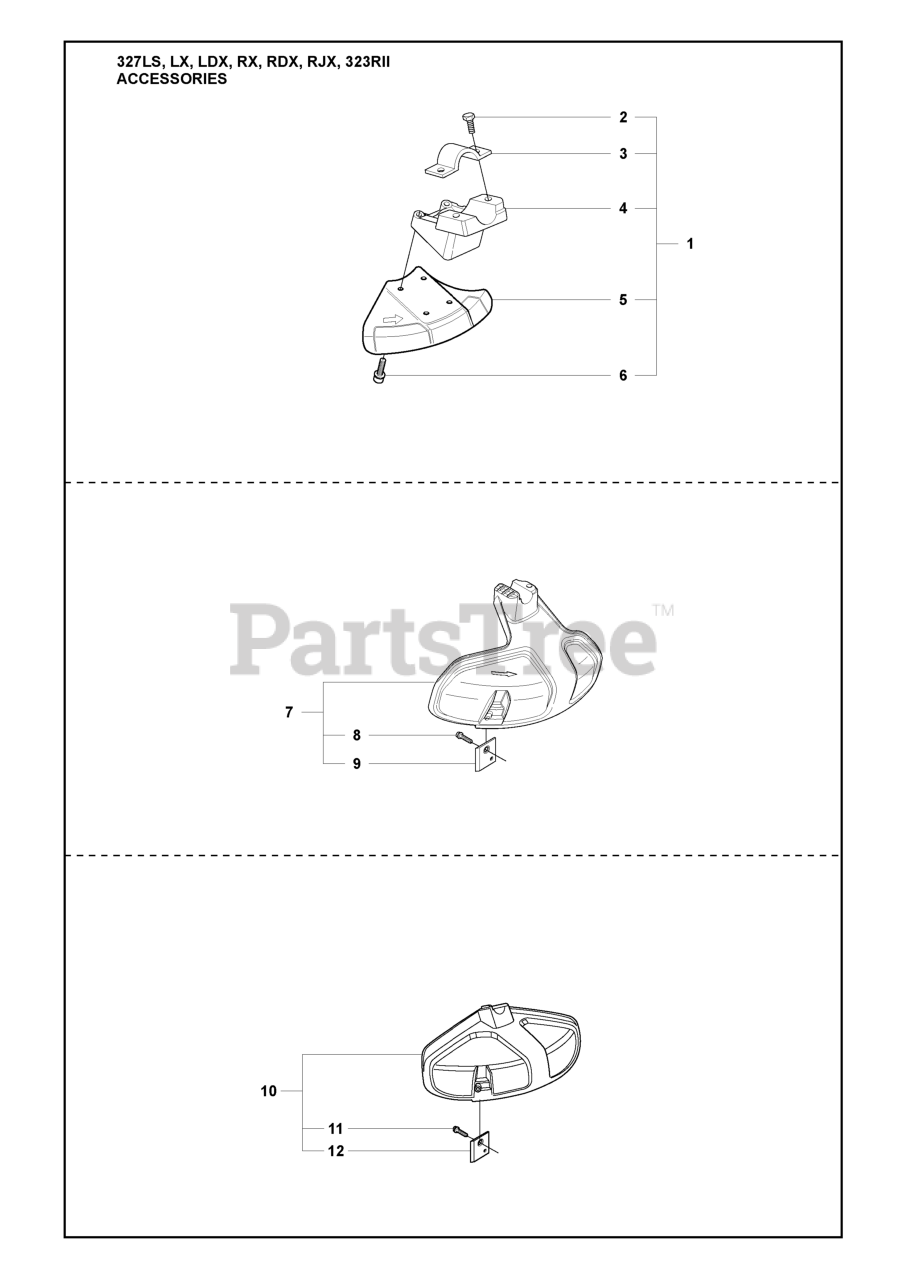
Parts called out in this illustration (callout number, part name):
1	TRIMMER GUARD ASSY
2	BOLT FLANGE - M6X20
3	CLAMP
5	BLADE GUARD
7	TRIMMER GUARD ASSEMBLY
9	LINE CUTTER
10	GRASS SHIELD
12	LINE CUTTER
